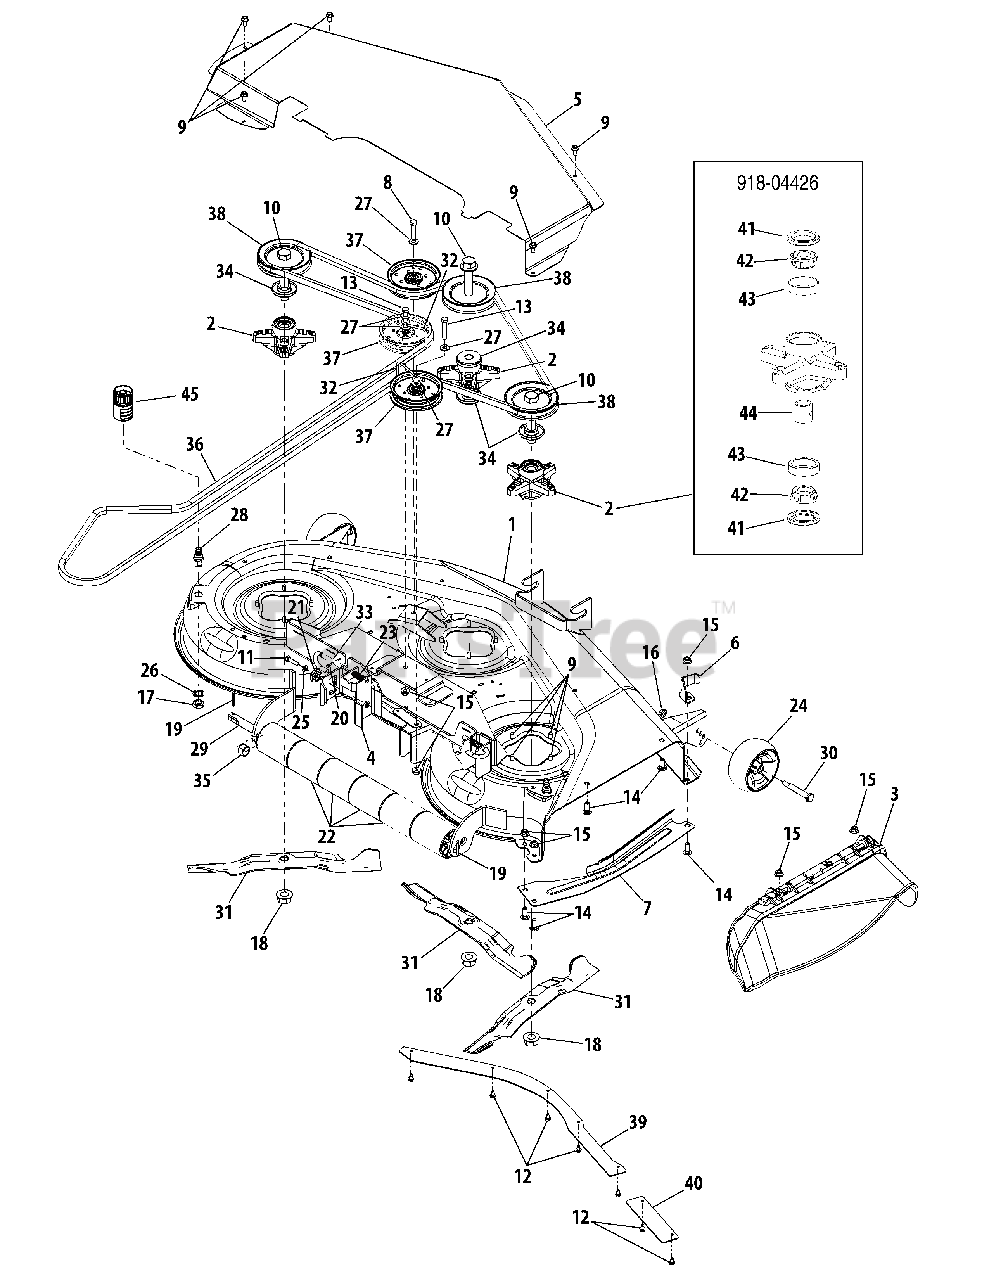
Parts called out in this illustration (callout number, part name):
2	Fitting, Lube, 3/16 Drive
3	Chute Assembly
8	Screw, Hex Cap, 3/8-16 x 1.75 Gr5
9	Screw, Hex Wash. Hd. Tapp, 5/16-18 x .75
10	Bolt, Spindle, 3/4-16 x 4.25
11	Screw, Hex Cap, 5/16-18 x 1.25 Gr5
12	Screw, Hex Wash. Hd. Tapp, 5/16-18 x .75
13	Screw, Hex Cap, 3/8-16 x 2.0 Gr5
14	Bolt, Carriage, 3/8-16 Gr1
15	Nut, Hex Insert Flange Lock, 3/8-16 GrF
16	Nut, Hex Flange Top Lock, 3/8-16 GrF
17	Nut, Hex M16 -1.5
18	Nut, Hex Flange Lock, 3/4-16 Gr8
19	Pin, Internal Cotter
20	Pin, Cotter, 1/8 x 1.25
21	Gear, Deck Adjustment
22	Roller, Deck
23	Spring, Compression, .531 x 1.75
24	Wheel, Deck Ball, 5.0
25	Washer, Lock, 5/16
26	Washer, Internal Toothe Lock, 5/8
27	Washer, Flat, .406 x .875x .059
28	Nozzle, Deck Wash
29	Shaft, .75 x 26.893
30	Bolt, Shoulder, .496 x 2.5:3/8-16
31	Blade, 17.9 2 in 1
32	Rod, Belt Keeper
33	Rod, Deck Release
34	Spacer, Deck Spindle
35	Spacer, .82 x 1.0 x .53
36	V-Belt, A Section x 184.25
37	Pulley, Idler, 4.25
38	Pulley, Spindle
41	Seal, Oil
42	Bearing, Cone
43	Cup, Bearing
44	Spacer, Bearing
45	Adapter, Water Nozzle
